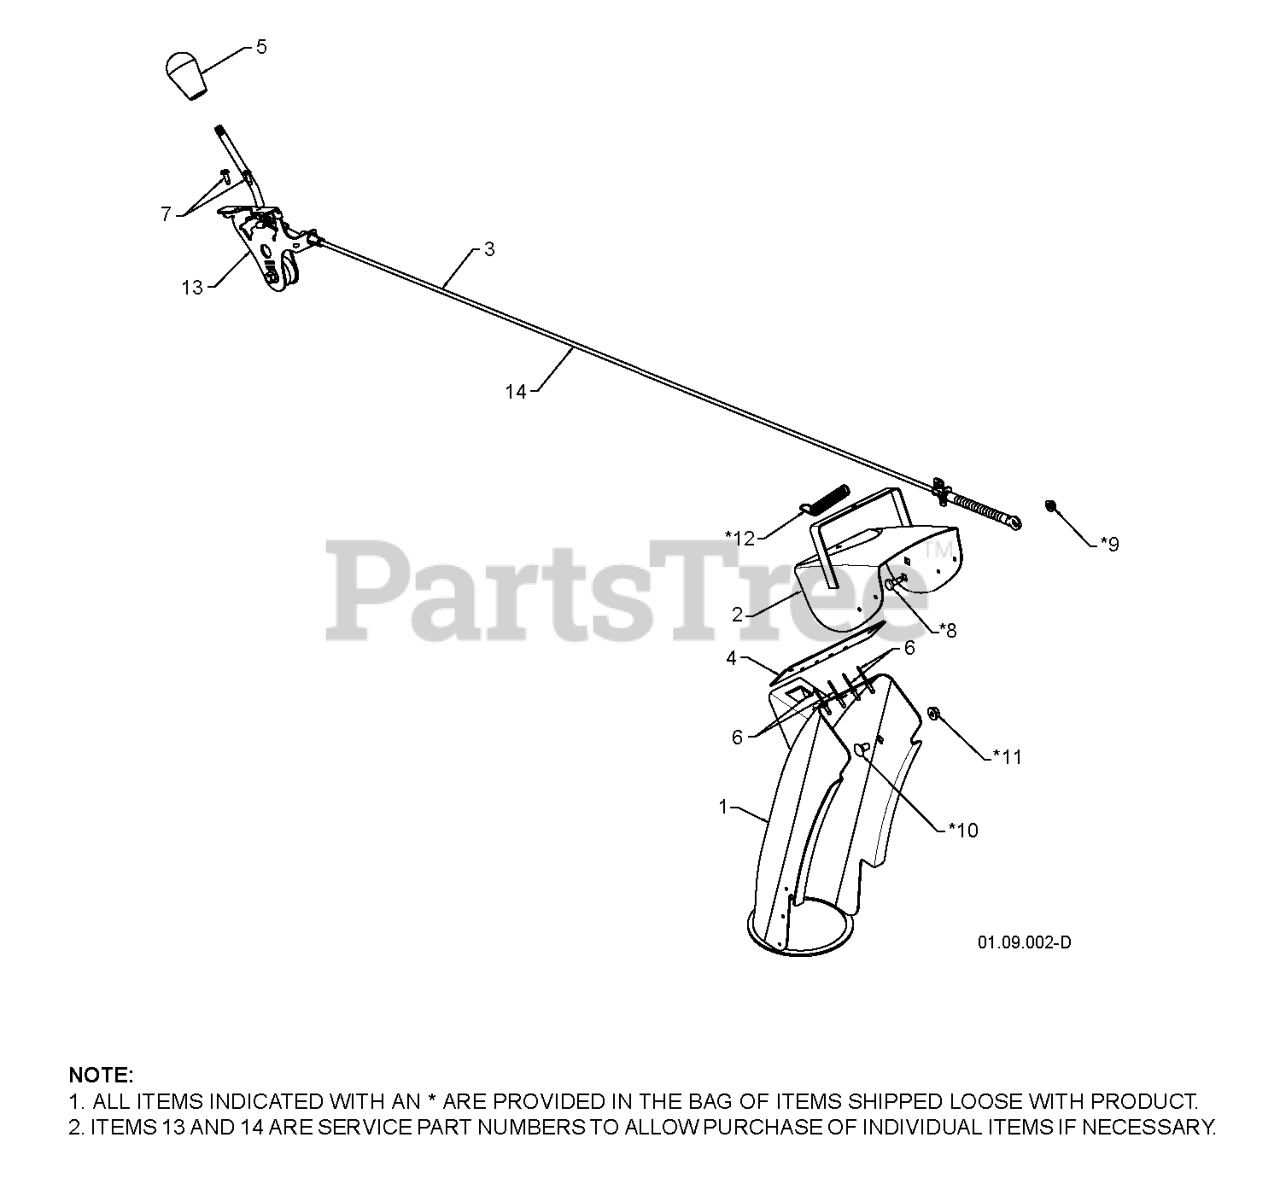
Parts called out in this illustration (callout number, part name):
1	CHUTE.WELDMENT
2	DEFLECTOR.WELDMENT.PNT.ORANGE
3	RP.CONTROL.ASM.DEFLECTOR.SNOW
4	SEAL.DEFLECTOR
5	KNOB LEVER, BLACK
6	RIVET BLIND
7	SCREW #10-24 X 5/8
13	RP CNTRL.HEAD.ASSEM.DEFLECTOR
14	RB SERVICE.CHUTE.DEF.CBL.BLK
